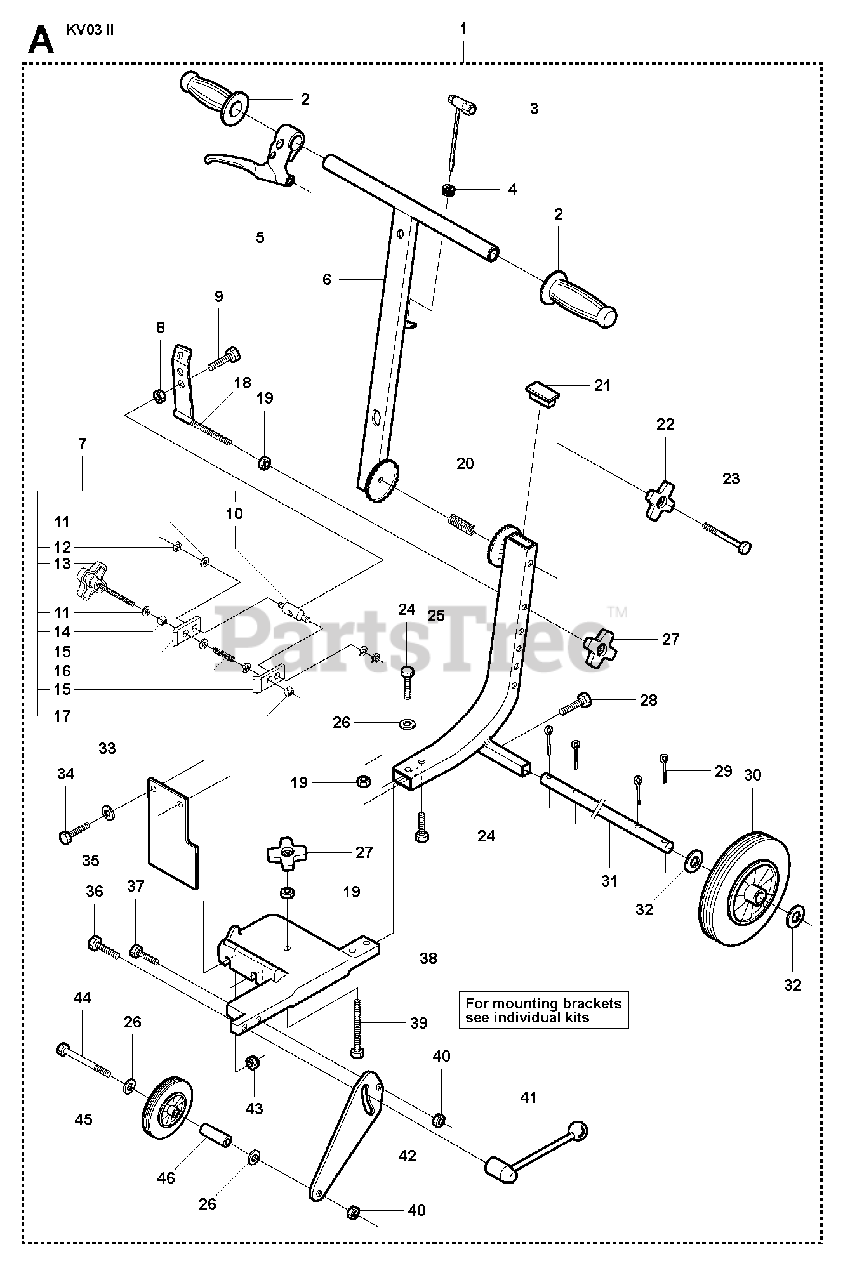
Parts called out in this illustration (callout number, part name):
1	CUTTING TROLLEYIncl. 2 - 46
3	COMBINATION WRENCH
4	ANTIVIBRATION ELEMENT
5	THROTTLE HANDLE
7	BRACKETIncl. 10 - 17
8	HEXAGON NUT
13	STEERING WHEEL
19	HEXAGON NUT
22	STEERING WHEEL
27	STEERING WHEEL
